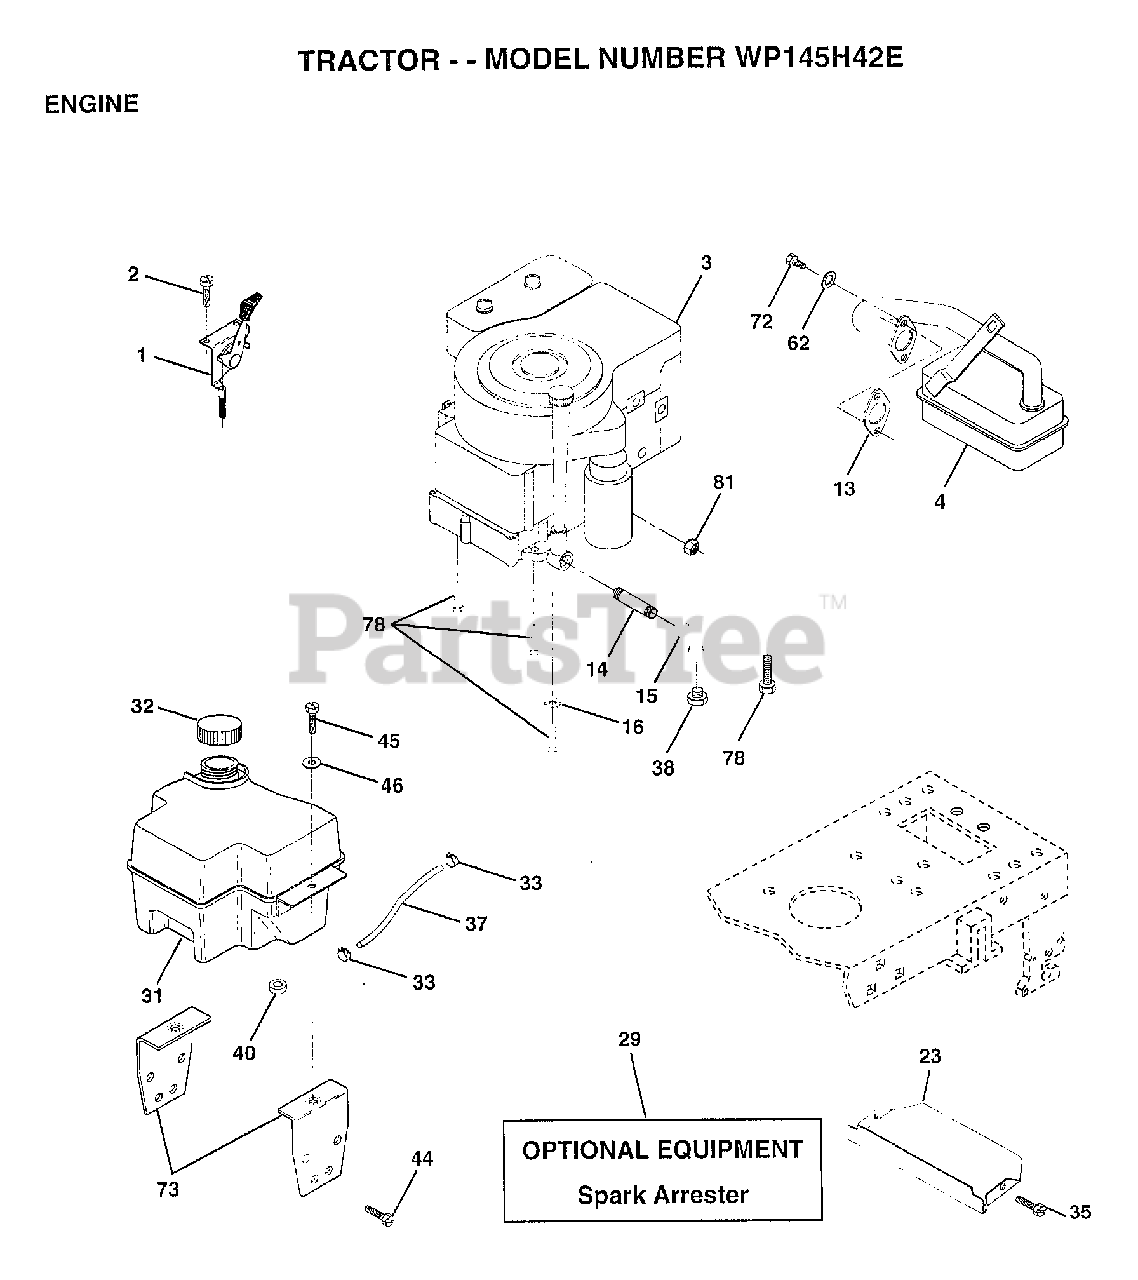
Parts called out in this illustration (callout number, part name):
1	"CONTROL,THROTTLE"
2	SCREW LT
4	MUFFLER
13	GASKET ENG 1 313 LD TIN PLATED
14	PIPE NIPPLE
15	ELBOW
16	LOCKWASHER
23	SHIELD.BRN/DBR.GD
31	TANK.FUEL.FRONT.
32	CAP ASM FUEL
33	HOSE CLAMP
35	SCREW
37	LINE FUEL
39	PAD IDLER TI
44	SCREW
45	SCREW HEX CRT
46	WASHER
62	LOCKWASHER
72	SCREW
73	BRACKET.SUPT.TANK
78	SCREW
81	NUT
